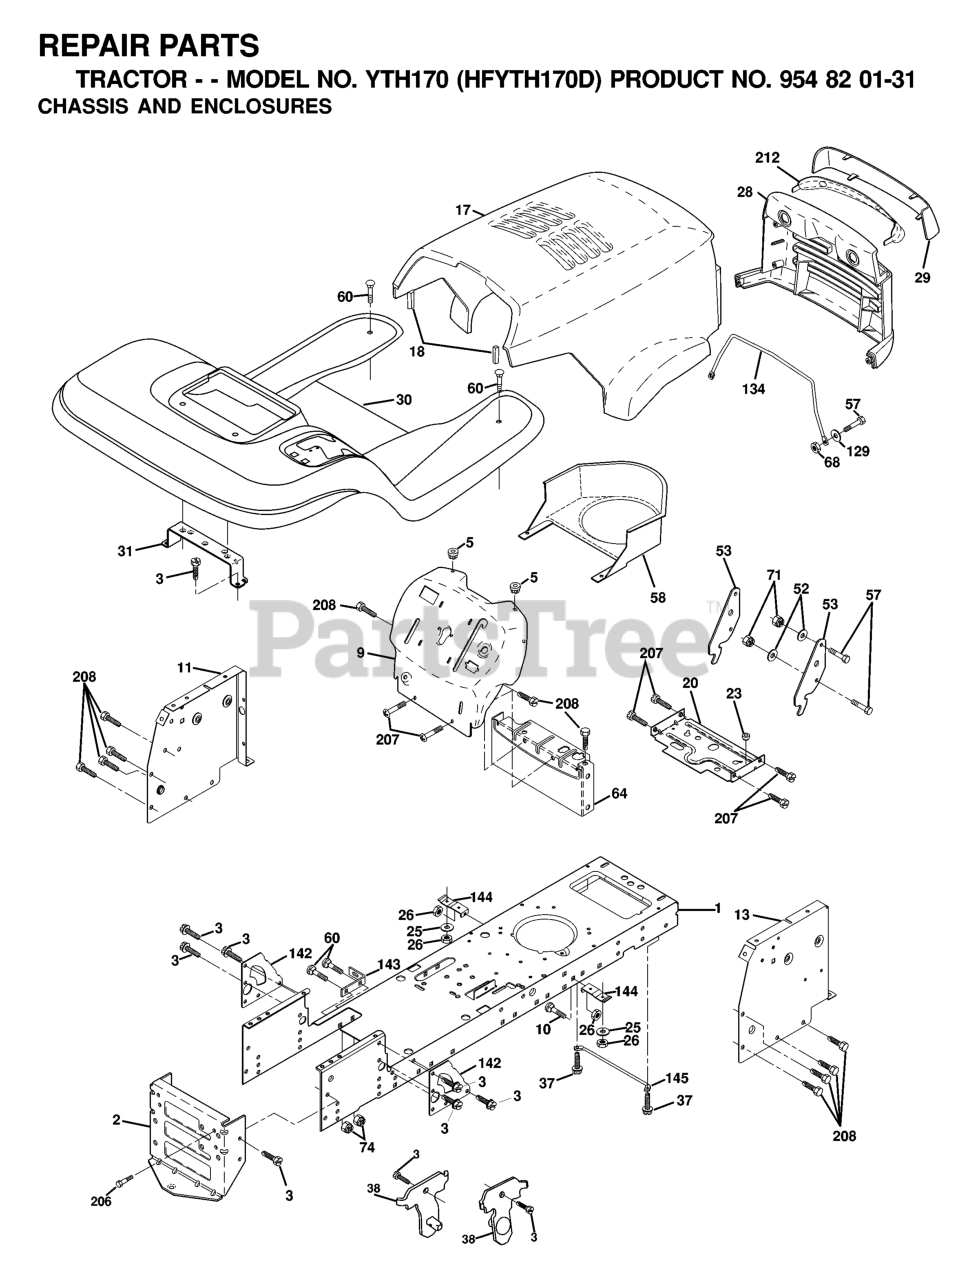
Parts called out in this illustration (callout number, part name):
2	DRAWBAR
3	SCREW 3/8-16X3/4
5	BUMPER.RUBBER.HOOD
10	BOLT D
11	PANEL DASH LH
13	DASH PANEL RH
17	HOOD
18	BUMPER HOOD T
20	PLATE MTG
23	BUSHING.SNAP.NYL.BLK.
25	WASHER
26	NUT
28	GRILL
29	LENS
30	FENDER FOOTREST
31	BRACKET.SUPPORT.FENDER
37	Screw 5/16-18 x 1/2 Hex, Self Tapping 5/16-18 x 1/2
38	BRACKET
53	BRACKET PNT PICK OFF LT/PL
57	BOLT
58	AIR DUCT P/L/LT
60	Bolt - Rd. Hd. Sq. Neckiage 3/8 16 x 3/4
64	DASH LOWER
68	NUT
71	NUT.CROWNLOCK.1/4
134	ROD SUPPORT HOOD LT/PL HUS.
142	PLATE
143	BRACKET, SWAY BAR
144	BRACKET FOOTREST
145	ROD PIVOT CHASSIS/HOOD
206	SHOULDER BOLT 5/16-18TT
207	SCREW, 5/16-18 X 1/2
208	SCREW 3/8-16X1/2
212	INSERT LENS REFLECTOR
